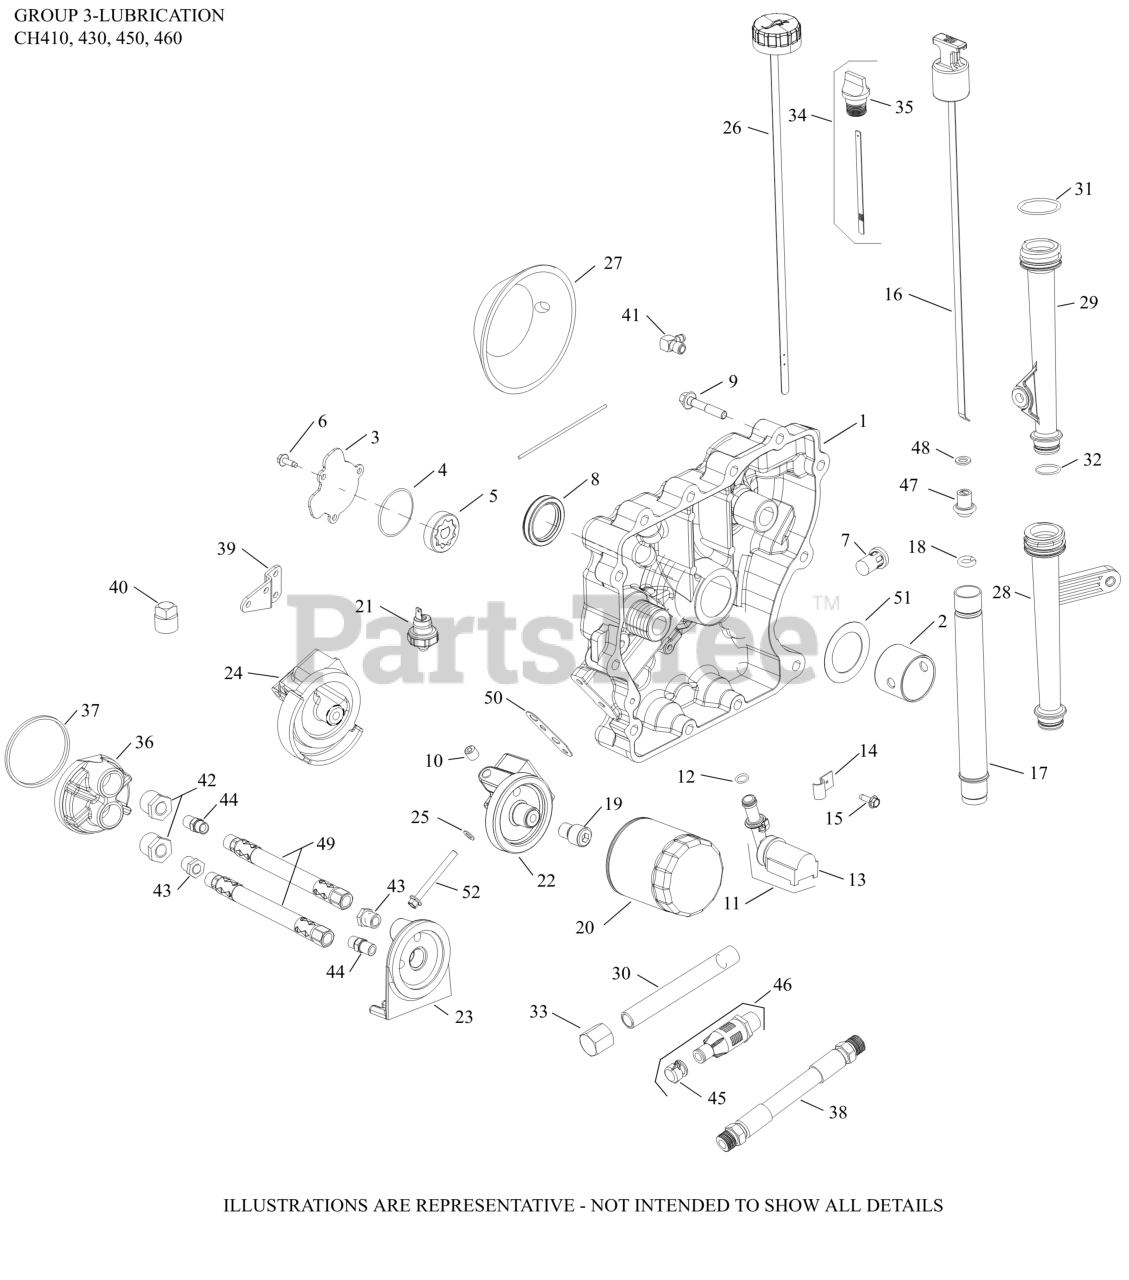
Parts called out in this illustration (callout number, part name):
1	CLOSURE PLATE ASSEMBLY
2	BEARING, CRANKSHAFT
3	COVER, OIL PUMP
4	O-RING (1.78" DIA)
5	PUMP ASSEMBLY, OIL-(#DSC)
6	SCREW, THREAD FORMING
7	VALVE, OIL PRESSURE RELIEF
8	SEAL, OIL
9	SCREW, FLG M8X1.25X45
10	PLUG, CTSK PIPE 1/8"
11	KIT, OIL PICK-UP
12	O-RING (.5" DIA)
13	PICK-UP, OIL
13	PICK-UP, OIL SCREEN
15	SCREW,FLG THD FRM M5X0.8X16-(#25086398S)
16	DIPSTICK-(#DSC)
17	KIT, OIL FILL TUBE - METAL
20	OIL FILTER
22	ADAPTER-(#DSC)
50	GASKET, OIL FILTER ADAPTER
52	SCREW, FLG M6X1.0X60
